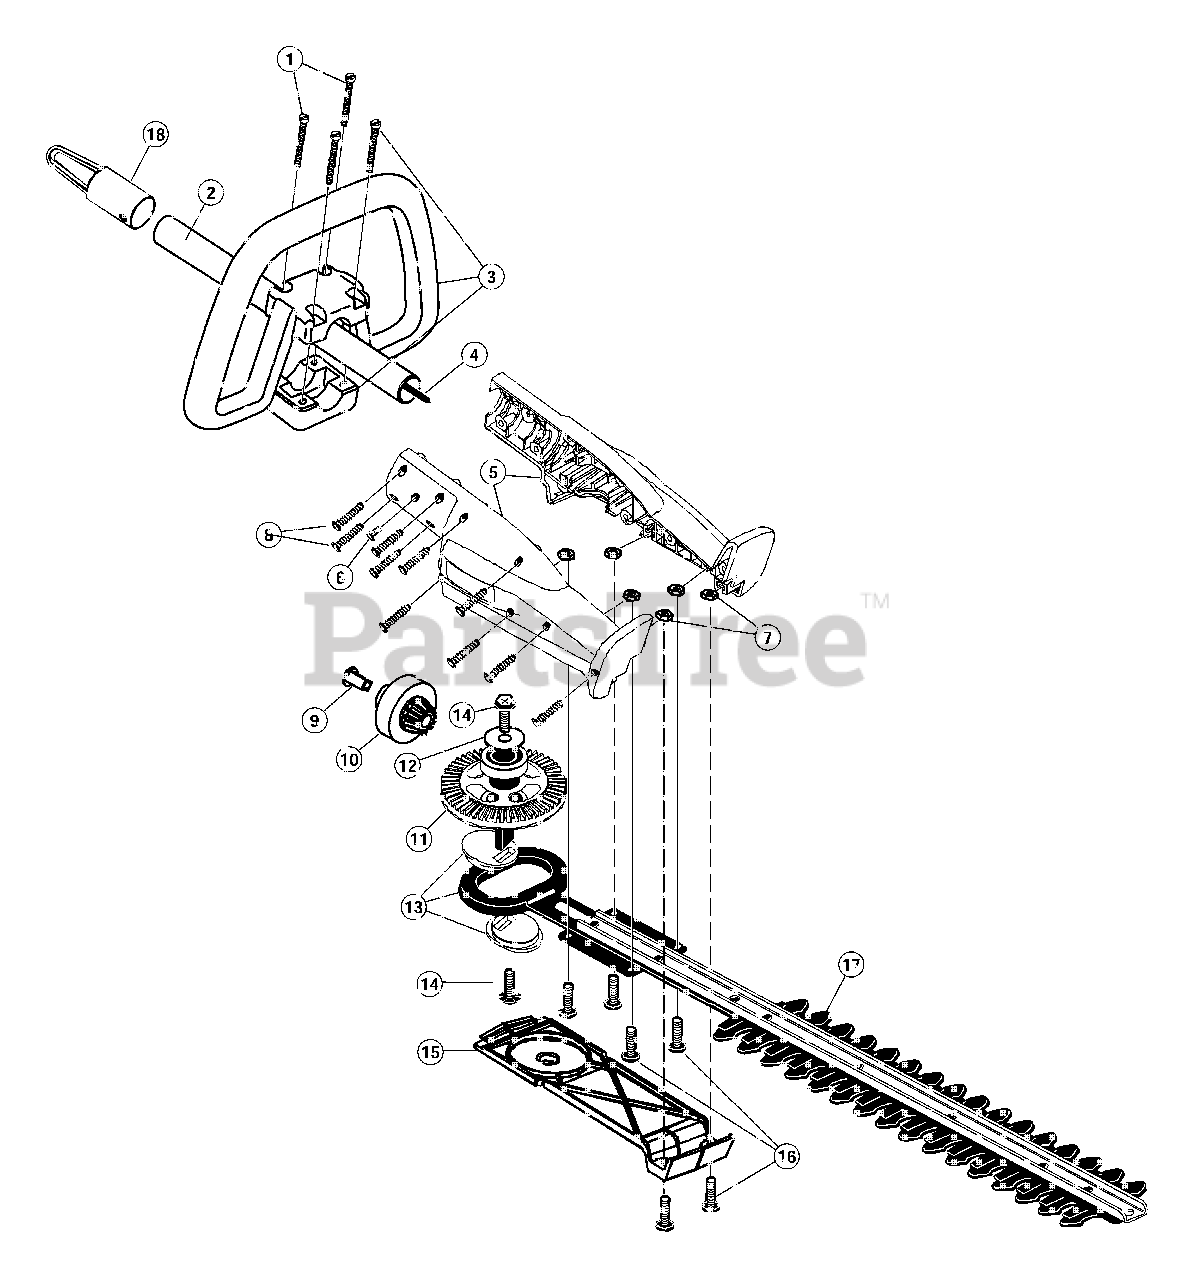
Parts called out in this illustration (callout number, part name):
2	Drive Shaft Housing Assembly
3	Loop Handle Assembly
4	Drive Shaft Assembly
5	Housing Set
6	Anti-Rotation Screw
8	Housing Screw
9	Insulator
10	Pinion Gear
11	Bevel Gear Asm
13	Cam Assembly
15	Bottom Plate
17	Cutting Blade Assembly
18	Hanger
